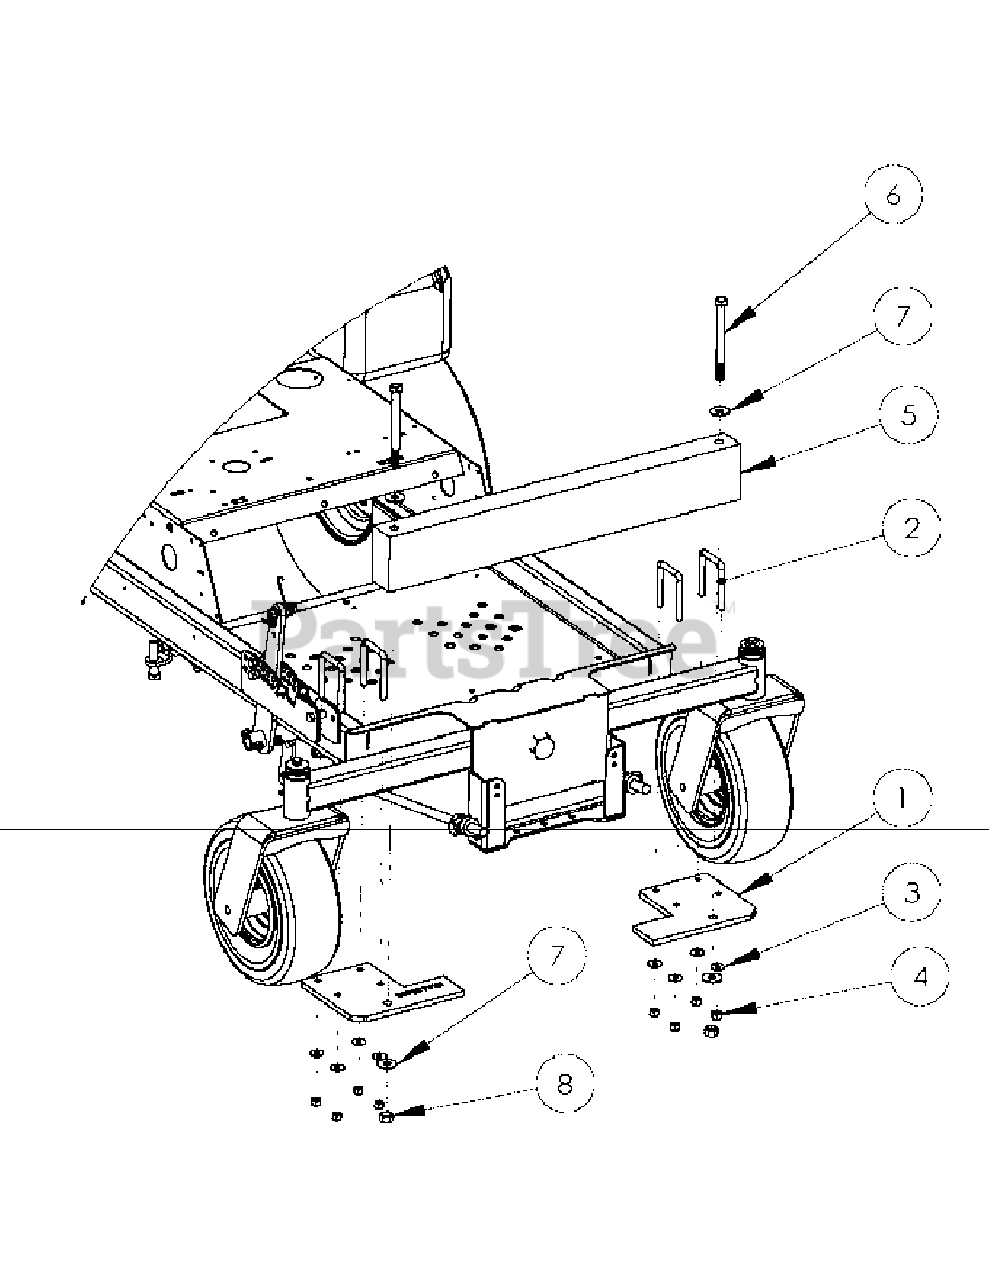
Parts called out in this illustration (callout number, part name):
1	48"-60" RECON WEIGHT BRACKET
3	FLAT WASHER 5/16"
4	HEX NUT, NYLON INSERT 3/8"-16
5	BAR, WEIGHT
6	CAP SCREW, 1/2"-13 X 5 1/2" LONG
7	FLAT WASHER 1/2"
8	HEX NUT, NYLON INSERT 1/2"-13
